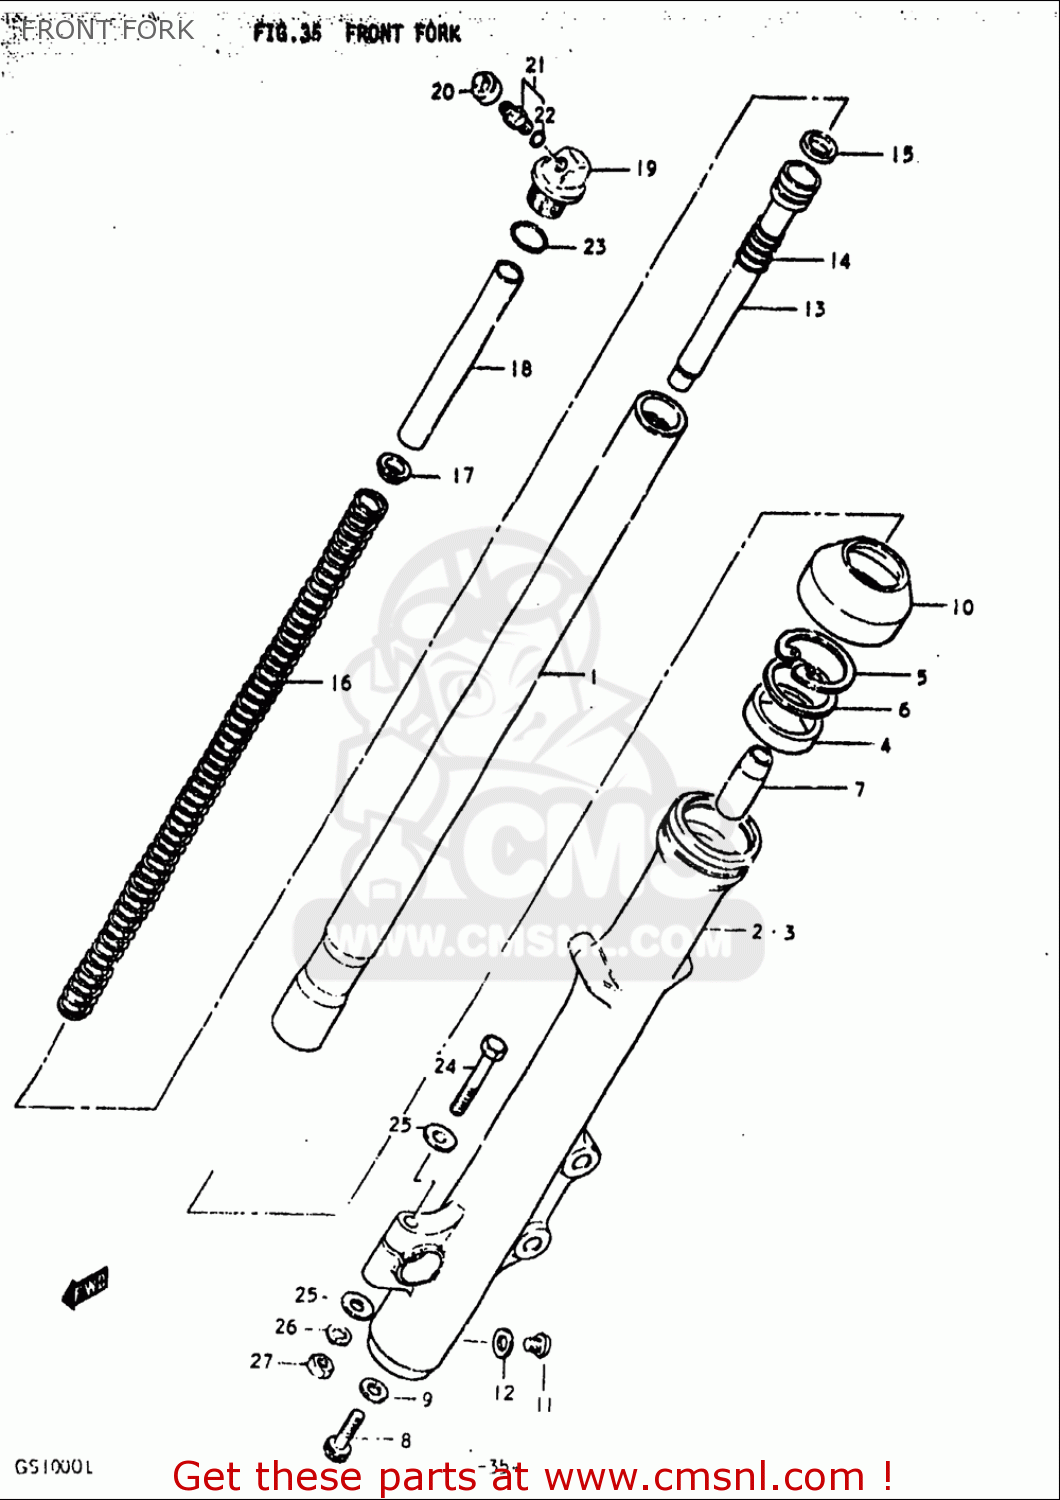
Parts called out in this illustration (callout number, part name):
4	SEAL,OIL
6	WASHER. FRONT FORK
8	BOLT,FORK CYLINDER(10X25)
9	GASKET (NAS)
10	SEAL,DUST
11	SCREW
12	GASKET,DRAIN,PLUG (NAS)
14	SPRING,REBOUND
15	RING,PISTON
17	GUIDE,FRONT FORK SPRING C
19	CAP
20	CAP,VALVE
21	VALVE
22	O RING
23	O RING
24	BOLT
25	WASHER
26	WASHER,LOCK
27	NUT
